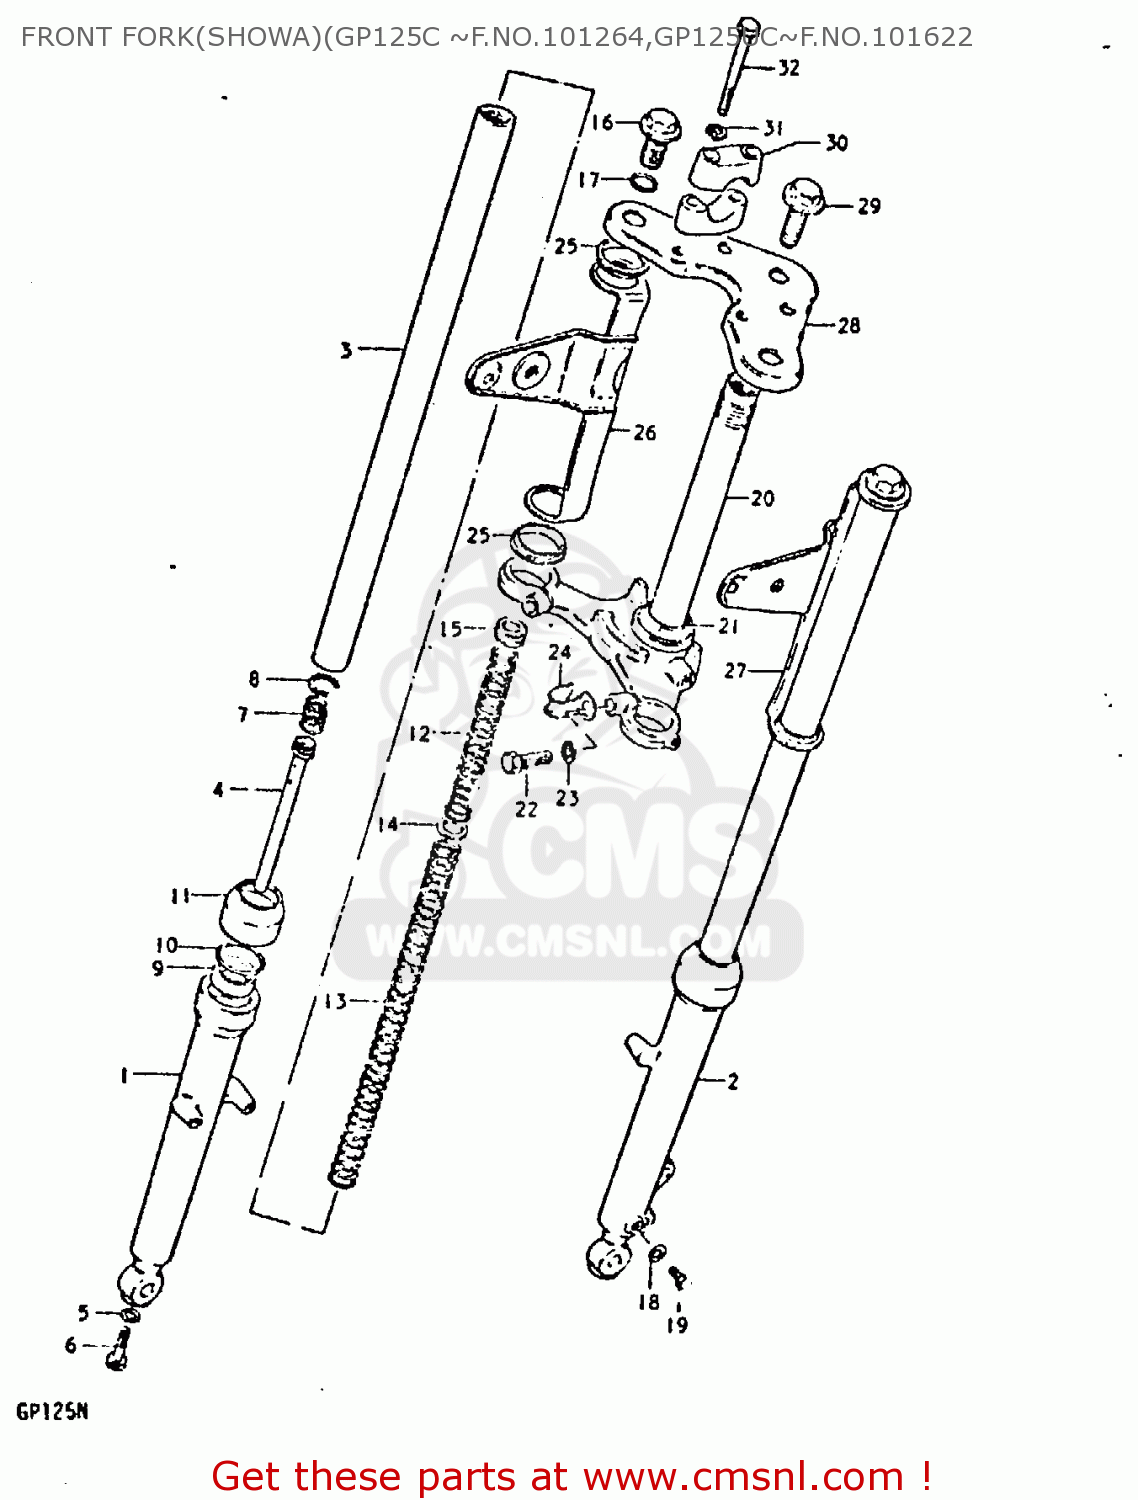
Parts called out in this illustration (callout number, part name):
1	OUTER TUBE, RH
2	OUTER TUBE, LH
3	TUBE, INNER
4	CYLINDER
5	GASKET (NAS)
6	BOLT
7	SPRING,REBOUND
8	RING,PISTON
9	OIL SEAL,FRONT FORK
10	RING,OIL SEAL STOPPER
11	BOOT
12	SPRING, NO.1
13	SPRING, NO.2
14	JOINT,SPRING
15	NUT,FORK SPRING,UPPER
16	CAP
17	O-RING,FORK INNER TUBE
18	GASKET,DRAIN,PLUG (NAS)
19	BOLT(6X8)
20	STEM, STEERING
21	RACE,STEERING OUTER LWR
22	BOLT 10X30
23	LOCK WASHER
24	CLIP,CABLE
25	CUSHION
26	BRACKET, HEADLAMP RH
27	BRACKET, HEADLAMP LH
28	STEM HEAD, STEERING
29	BOLT
30	HOLDER,HANDLE UPR
31	LOCK WASHER
32	BOLT 8X55
